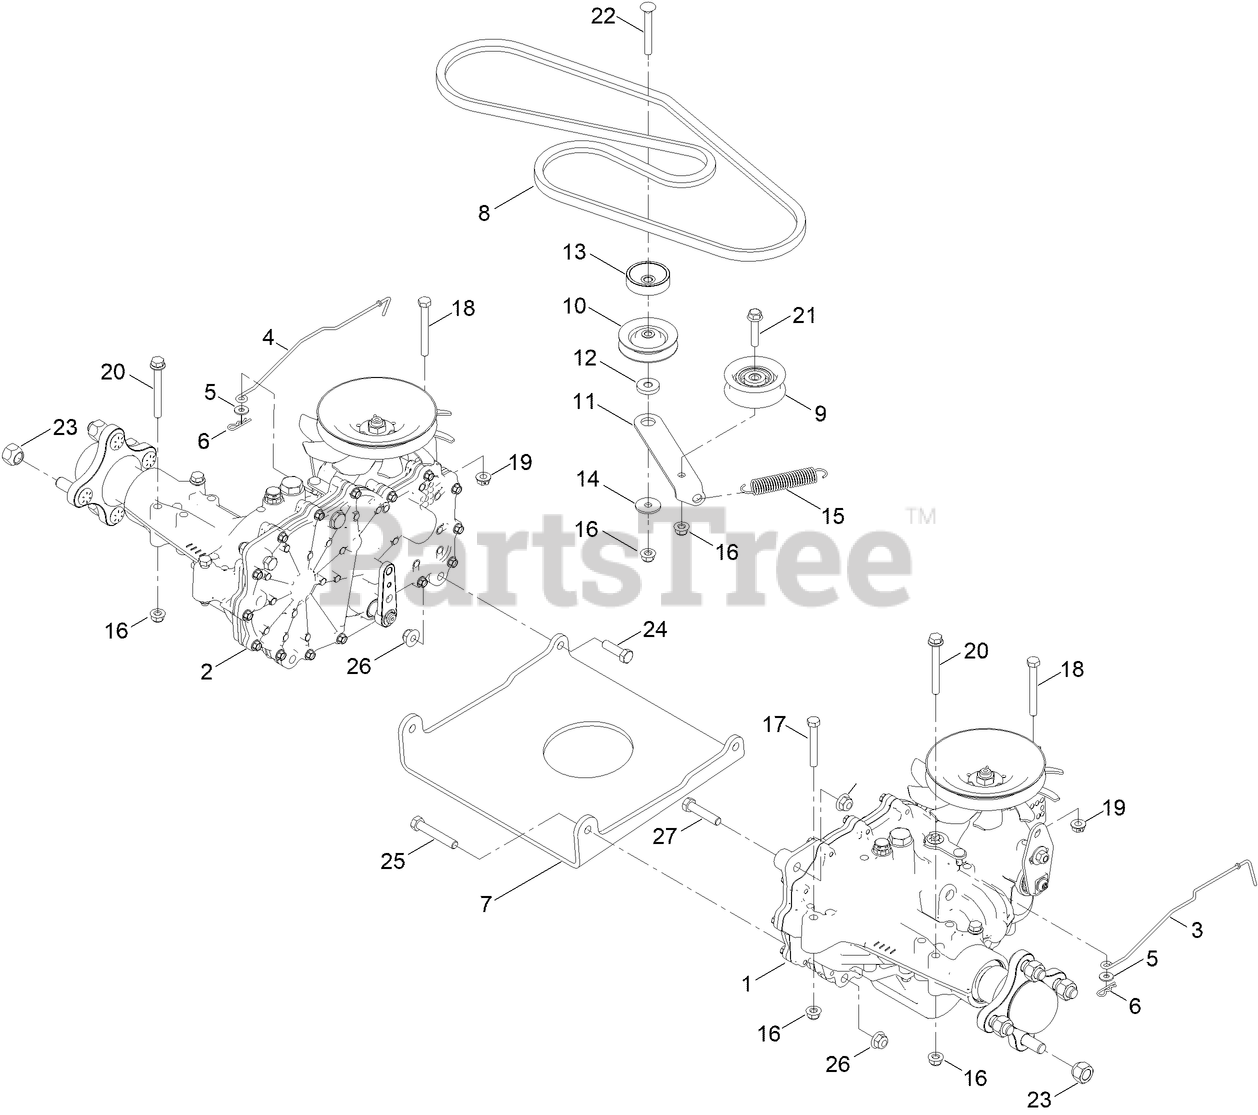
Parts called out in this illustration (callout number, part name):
1	RH HYDRO TRANSMISSION ASM
2	LH HYDRO TRANSMISSION ASM
3	ROD-BYPASS, LH
4	ROD-BYPASS, RH
5	WASHER
7	PLATE-HYDRO
8	V-BELT (A SEC 65.30 EL)
9	PULLEY-IDLER, FLAT
11	ARM-IDLER
12	SPACER-IDLER ARM
13	SPACER
14	WASHER-PIVOT
15	SPRING-PEDAL, RETURN
16	NUT-HF, NI
17	SCREW-HH
18	SCREW-HH SPCL
19	NUT-HF
20	SCREW-HHF
21	SCREW-HHF
22	SCREW-CARR
23	NUT-LUG
24	SCREW-HH
25	SCREW-HH
26	NUT-HF, NI
27	SCREW-HH
